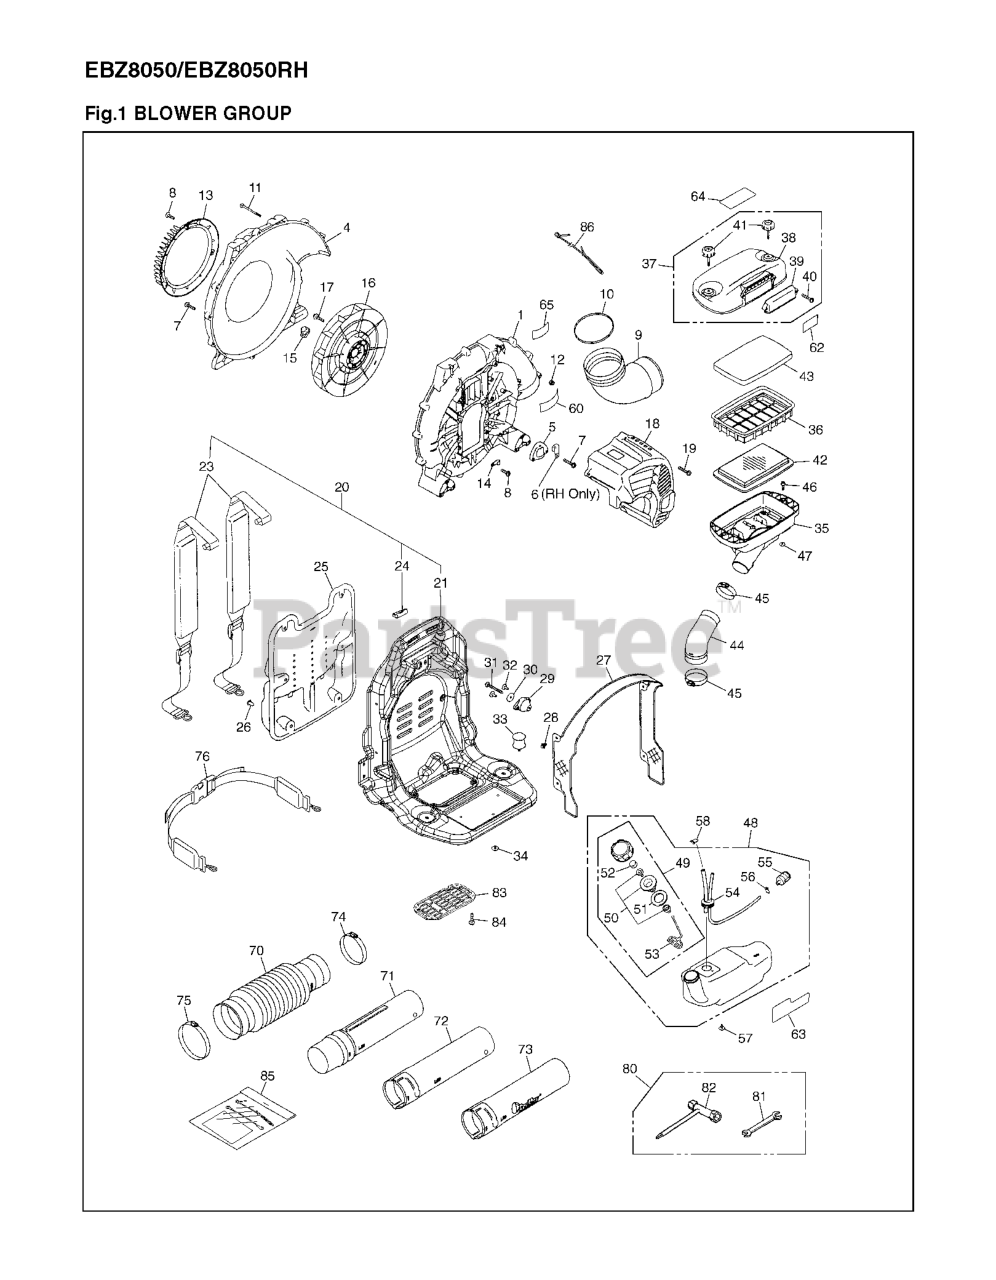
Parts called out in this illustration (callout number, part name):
1	VOLUTE CASE(RP 848-L58-55A3
4	VOLUTE COVER
5	ELBOW
6	CLAMP
9	ELBOW
10	0-RING
13	COVER (FUNNEL)
14	CLAMP
15	CAP
17	BOLT
18	ENGINE COVER(R-848L5831A2)
20	FRAME (RPLS 848L5M3500)
21	FRAME EBZ8001(R-848L583513,14)
23	BAND ASSY (RPLS 848L583611)
24	CLIP
25	PAD
26	CLIP (RPLS 3490-21320)
27	NET COMP
28	RP CLIP
29	DAMPER UPPER
30	WASHER
31	BOLT
33	DAMPER
37	COVER ASSY
41	KNOB BOLT-RED
42	ELEMENT
43	ELEMENT
45	CLAMP(F64)
46	BOLT
48	TANK ASSY
49	ASSY FUEL CAP
50	HOLDER-A
54	PIPE COMP
55	FILTER ASSY
56	CLIP
58	CLIP
60	LABEL,CAUTION
62	LABEL EBZ8050 848L6K90R0
71	%SWIVEL JOINT USE 848L586511
73	PIPE END (RPLS 848L5865E0)
74	CLAMP(F96)
75	CLAMP(F115)
76	BAND ASSY (RPLS 848L583620)
80	TOOL-SET
81	SPANNER,8x10(RPLS 090100810
82	SOCKET
85	CABLE KIT
86	CORD, ANTISTATIC
